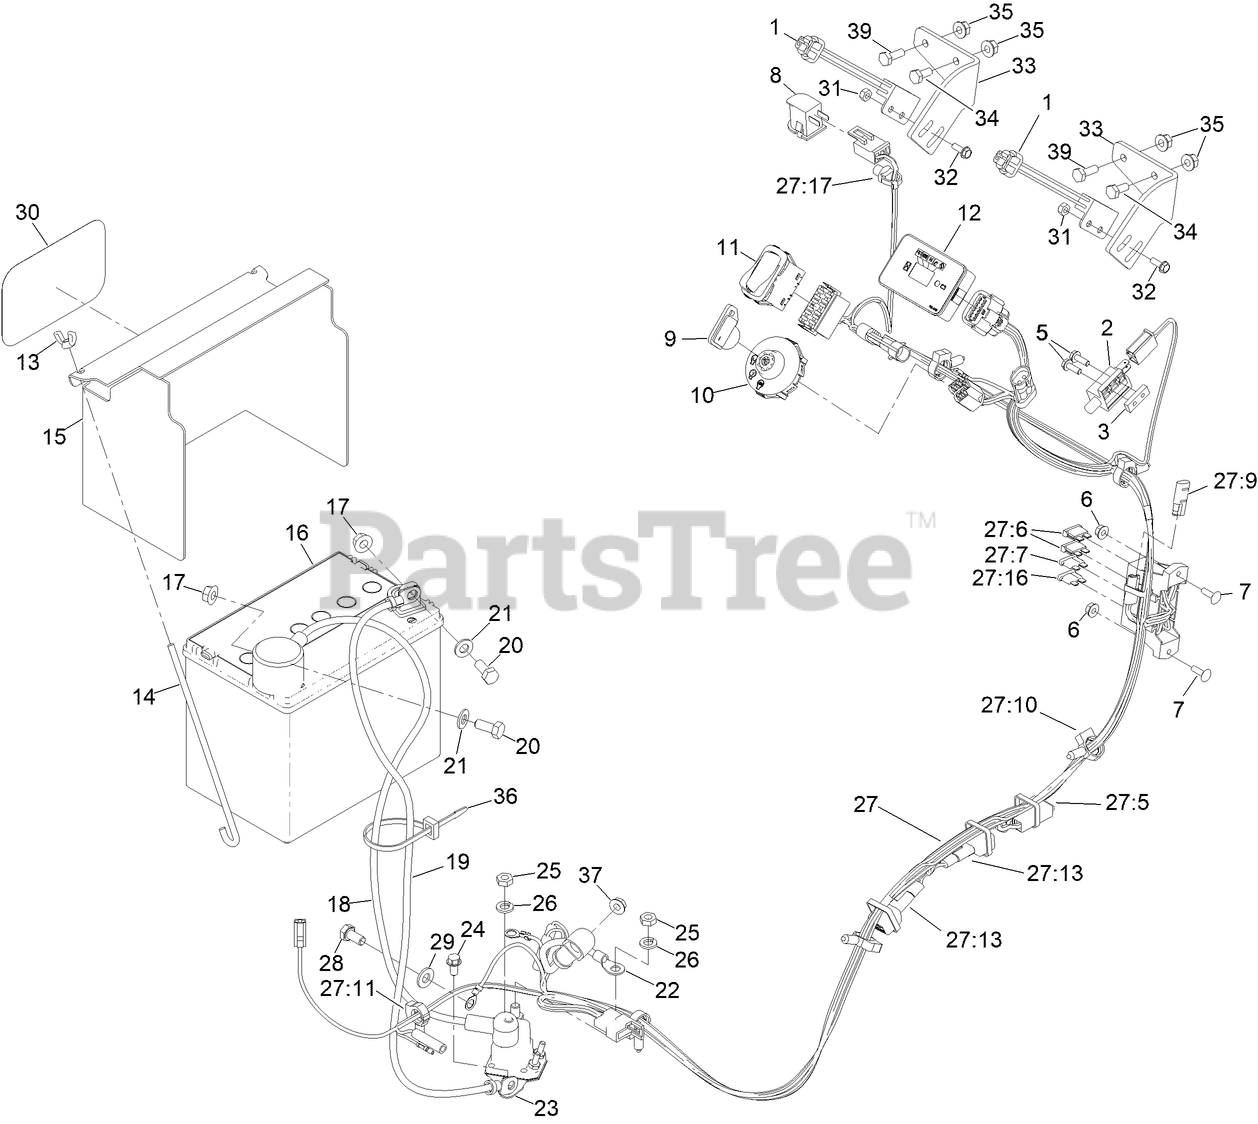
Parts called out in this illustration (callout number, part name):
1	SWITCH-PROXIMITY
2	SWITCH-CLOSED, NORMALLY
3	PLATE-TAPPED
5	SCREW-SHWH
6	NUT-LOCK, FLANGE
7	BOLT-CARR
8	SWITCH-BAIL
9	KEY-IGNITION
10	SWITCH-IGNITION
11	SWITCH-ROCKER, (ON)-ON-OFF
12	MODULE-HOUR METER
13	WINGNUT
14	BOLT-HOLDDOWN
15	COVER-BATTERY
16	BATTERY-DRY
17	NUT-HHF, SMOOTH
18	CABLE-BATTERY, POSITIVE
19	CABLE-GROUND, NEGATIVE
20	SCREW-HH
21	WASHER-PLAIN
22	CABLE-BATTERY, RED
23	SOLENOID
24	SCREW-HWH
25	NUT-JAM
26	WASHER-LOCK
27	HARNESS-WIRE, MAIN
27:5	FUSE-BLADE, 30 AMP
27:6	FUSE-BLADE, 15 AMP
27:7	FUSE-BLADE, 10 AMP
27:9	CAP-PLUG
27:10	CLIP-TUBING, HARNESS
27:11	CLIP-HARNESS
27:16	FUSE-BLADE, 5 AMP
27:17	CLIP-TIE
28	SCREW-HH
29	WASHER-PLAIN
30	DECAL
31	NUT-LOCK, NI
33	BRACKET-MOUNT, SWITCH
34	SCREW-HH
35	NUT-HHF
36	TIE-CABLE
37	NUT-HF
39	SCREW-HH
